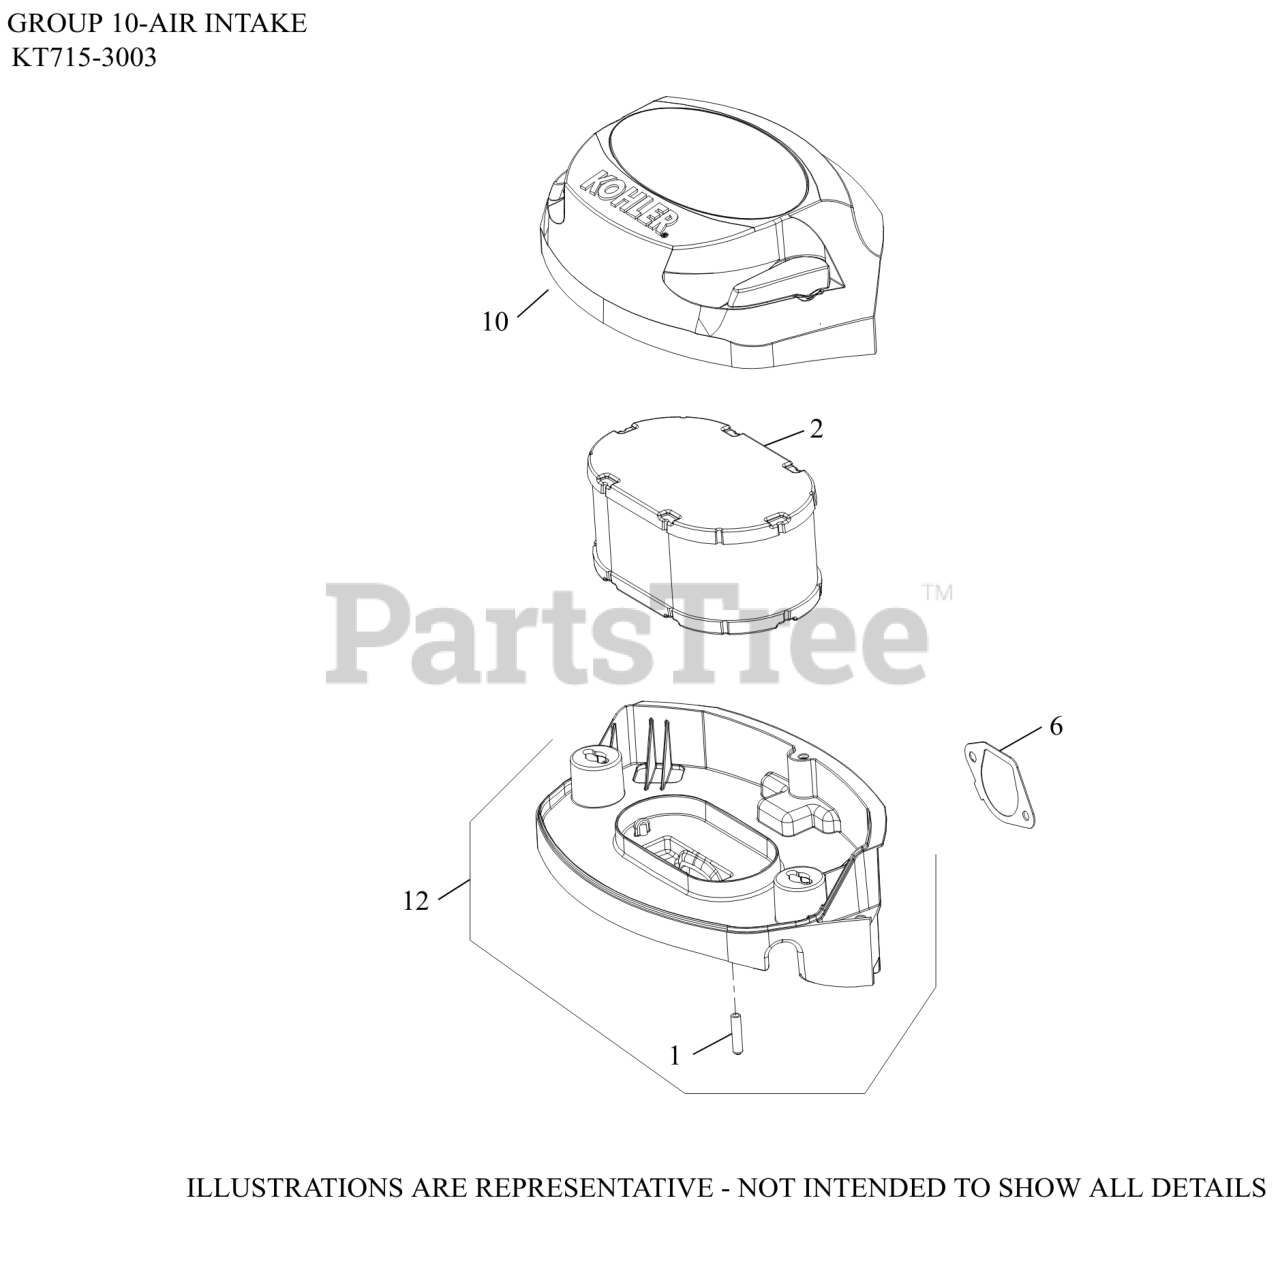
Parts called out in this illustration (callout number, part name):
1	CAP, MASKING
2	ELEMENT, AIR FILTER
6	GASKET, AIR CLEANER BASE
10	COVER ASSY, AIR CLEANER
12	BASE ASSY, AIR CLEANER
